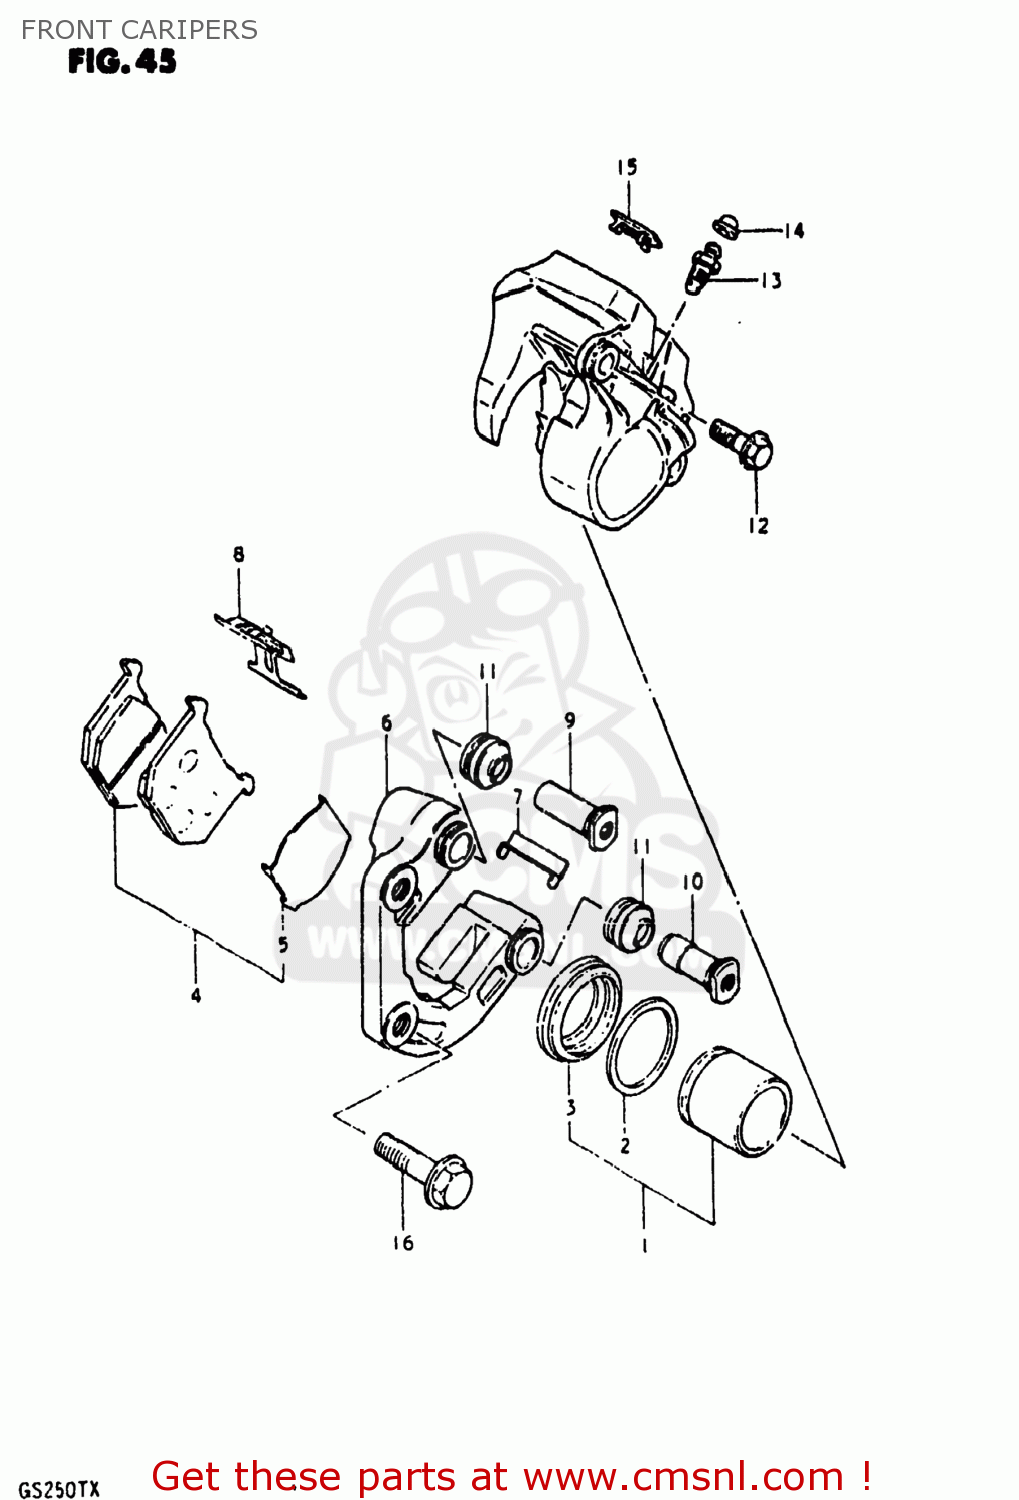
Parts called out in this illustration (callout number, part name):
1	PISTON SET
2	SEAL,FR CALIPE
3	BOOT,PISTON
4	PAD SET (MCA)
5	SHIM,PAD
6	CARRIER,CALIPER,LEFT
7	GUIDE,PAD
8	SPRING,PAD
9	AXLE NO.1
10	AXLE NO.2
11	BOOT,AXLE
12	BOLT,CALIPER HOUSING
13	BLEEDER
14	CAP,BREATHER
15	COVER,INDICATOR
16	BOLT(10X37)
